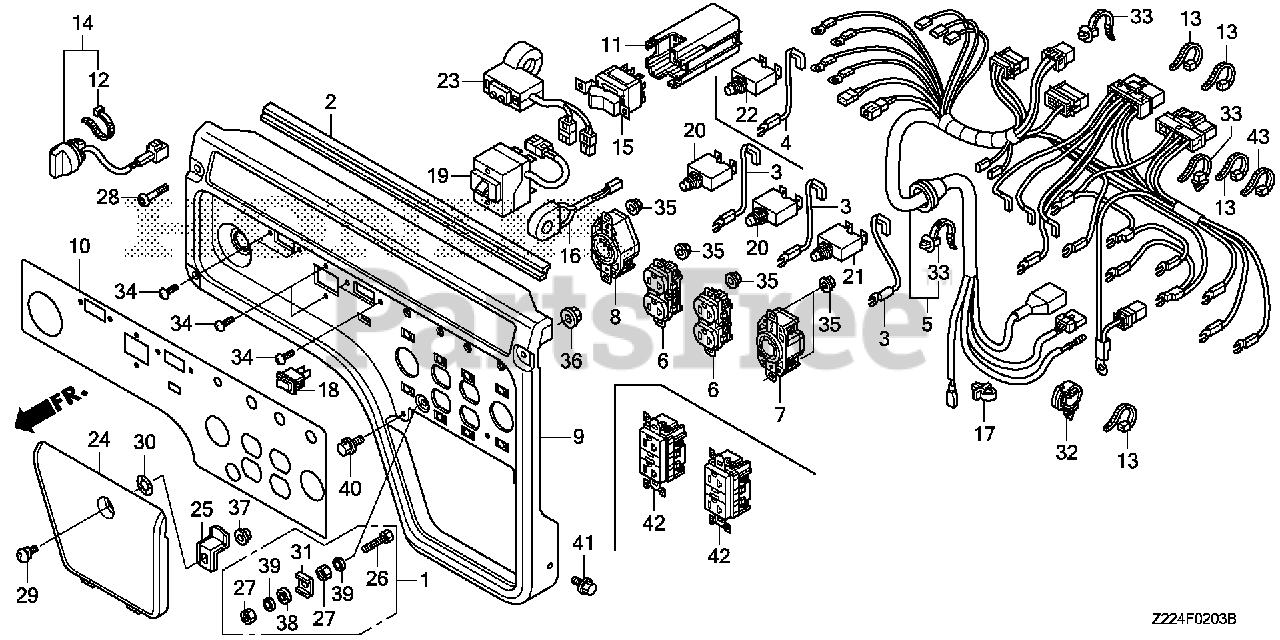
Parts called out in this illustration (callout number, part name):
1	TERMINAL SET, GROUND
2	RUBBER, CONTROL PANEL
3	SUB-WIRE ASSY. (A)
4	SUB-WIRE ASSY. (A)
5	WIRE HARNESS ASSY., CONTROL (EB-A1)
7	RECEPTACLE (30A-125/250V)
8	RECEPTACLE (30A-125V)
9	PANEL, CONTROL (EB-A1) *R280* (POWER RED)
10	MARK, PANEL (EB-A1)
11	CONNECTOR (12P)
12	BAND
13	TIE, CABLE (C)
14	SWITCH ASSY., ENGINE STOP
15	SWITCH ASSY., VOLT CHANGE
16	SENSOR ASSY. (CT)
17	HOLDER, STOP SWITCH WIRE Use up to Engine SN 2056819.
18	SWITCH, AUTO-THROTTLE (OTAX)
19	BREAKER, CIRCUIT (21A)
20	PROTECTOR, CIRCUIT (20A)
21	PROTECTOR, CIRCUIT (30A)
22	PROTECTOR, CIRCUIT (30A)
23	RELAY ASSY. (GFCI)
24	COVER (LOWER)
25	LOCK PLATE, COVER (LOWER)
26	BOLT, HEX. (6X28)
27	NUT, HEX. (6MM)
28	BOLT, SOCKET (8X22)
29	BOLT, MAINTENANCE LID LOCK
30	WASHER, WAVE (12MM)
31	RETAINER (6MM)
32	CLIP, WIRE HARNESS
33	CLIP, HARNESS BAND (145MM) (BLACK)
34	SCREW, PAN (4X6)
35	NUT, FLANGE (4MM)
36	NUT, FLANGE (6MM)
37	NUT, FLANGE (6MM)
38	WASHER, PLAIN (6MM)
39	WASHER, SPRING (6MM)
40	BOLT, FLANGE (6X14)
41	BOLT, FLANGE (6X10)
42	RECEPTACLE (20A-125V) (GFCI)
43	TIE, CABLE (C)
